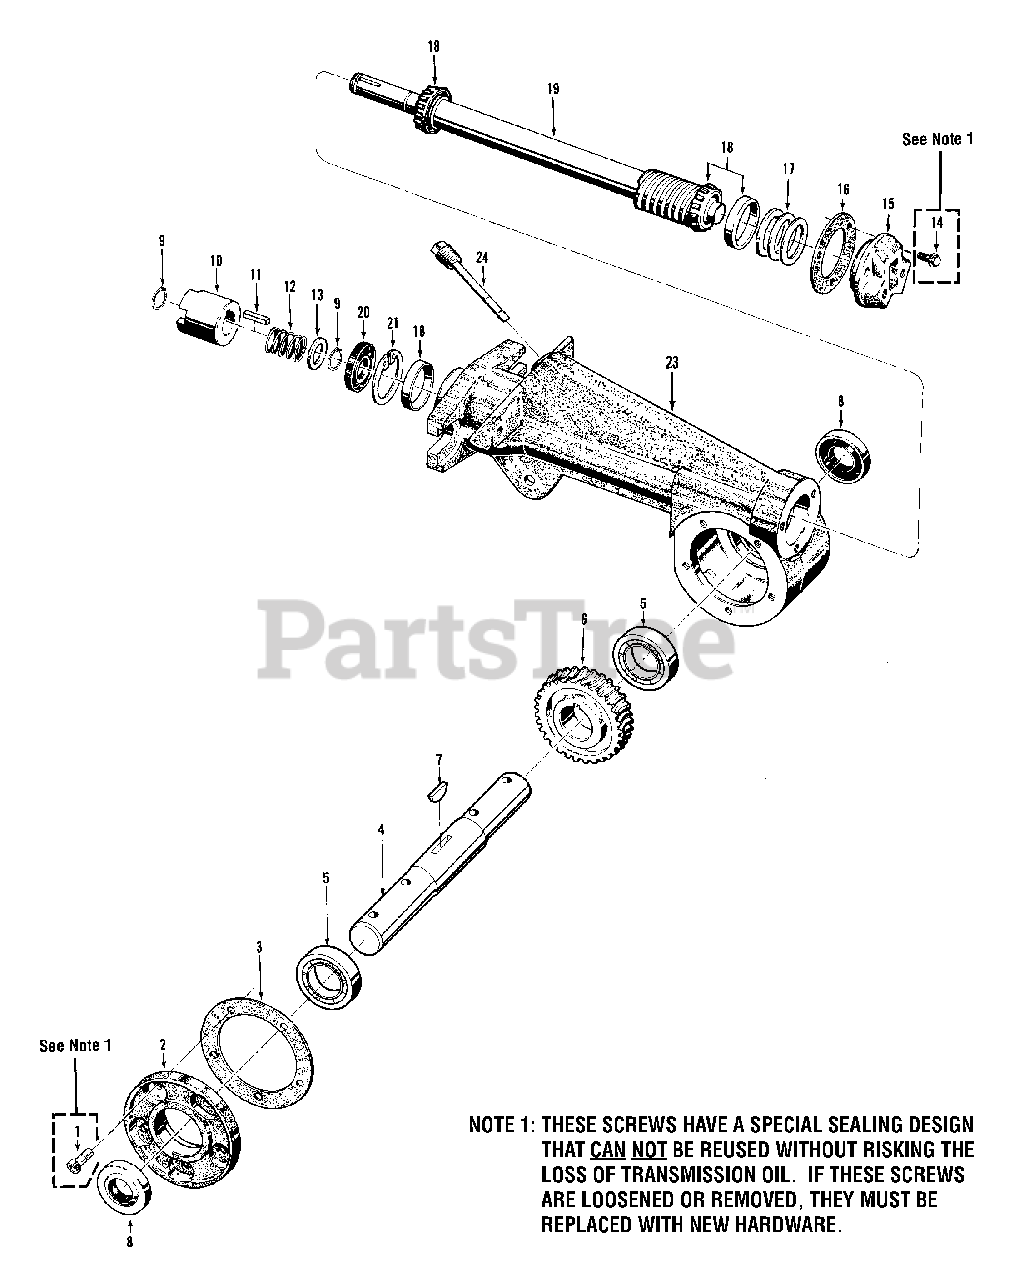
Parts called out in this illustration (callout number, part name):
1	Screw-self-sealing, 1/4"-20 x 5/8"
2	Cover-tiller housing
3	Gasket-tiller housing cover, .010" thick
3	Gasket-same as above, .030" thick
4	Shaft-tiller tine
5	Ball Bearing
6	Worm Gear-bronze, tiller tine shaft
7	Key-tiller tine shaft, woodruff key
8	Seal-oil, tiller tine shaft
9	Retaining Ring-external
10	Dog Clutch-tiller drive shaft
11	Key-3/16" x 1"
12	Spring-dog clutch
13	Shim-dog clutch, 1/16"(.62") thick
14	Screw-self-sealing,1/4"-20 x 7/8"
15	Cap-rear bearing
16	Gasket-rear bearing cap
17	Shim-front bearing cap, .010" thick
17	Shim-same as above, .030" thick
17	Shim-same as above, .005" thick
17	Shim-same as above, .062" thick
18	Bearing & Race
19	Shaft-main tiller drive
20	Seal-oil, drive shaft, front
21	Retaining Ring-internal
23	Housing-tiller attachment (Empty housing without shafts, gears, seals, dipstick, etc.)
24	Dipstick-oil, tiller attachment
